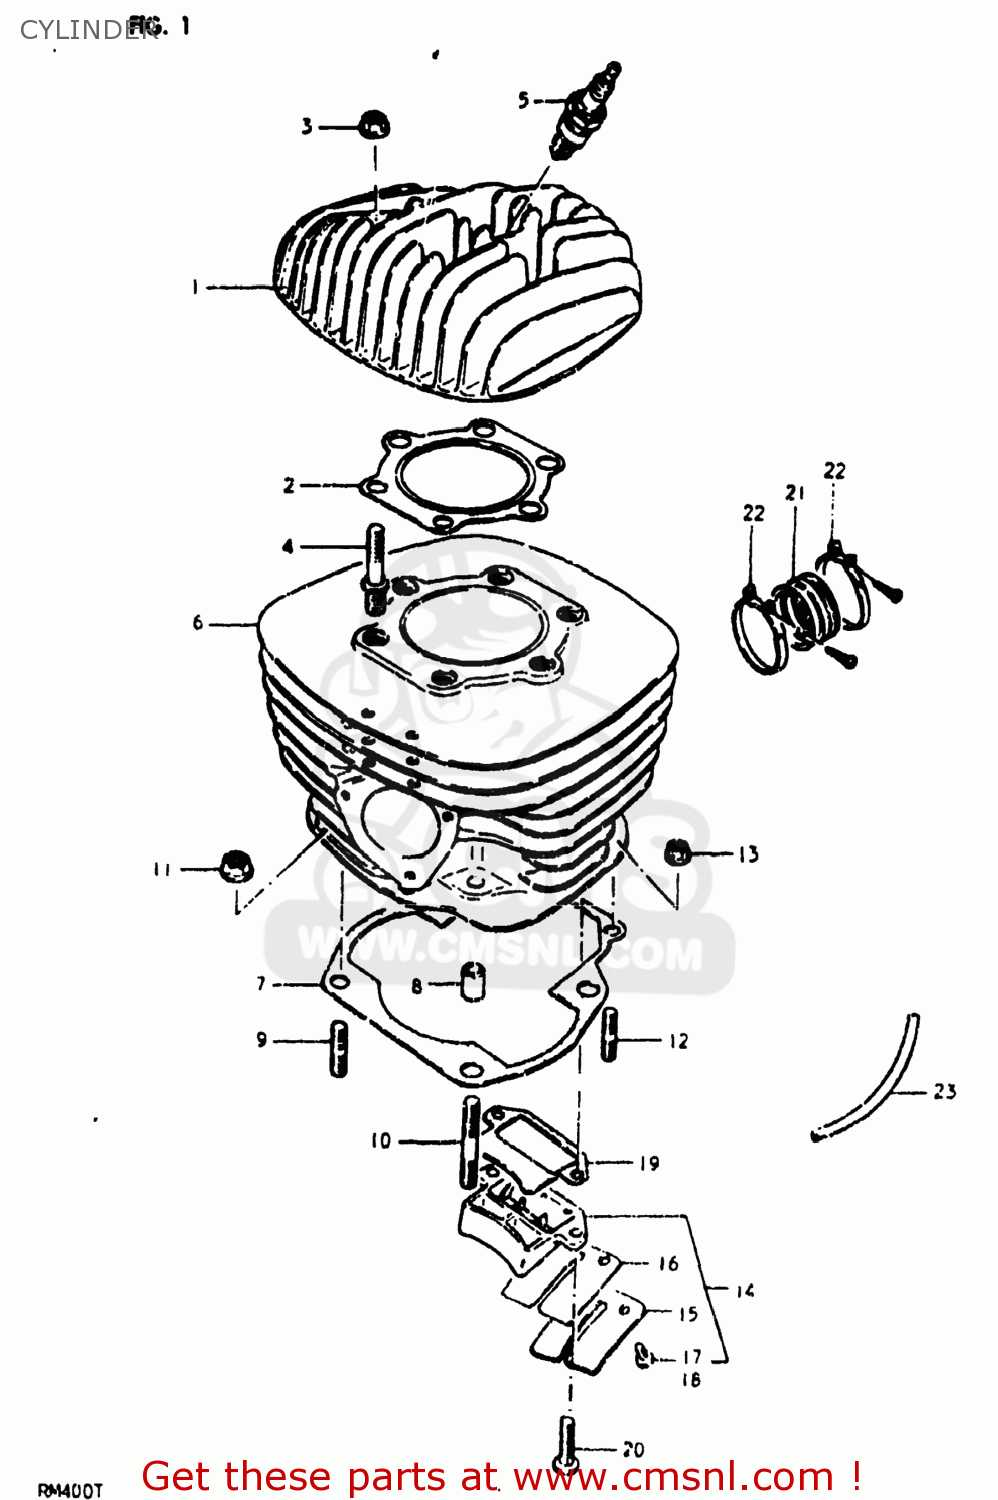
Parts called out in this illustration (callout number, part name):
1	HEAD,CYLINDER
2	GASKET,CYLINDER HEAD
3	NUT
4	STUD
5	PLUG,SPARK(NGK B-8EN)
6	CYLINDER
7	GASKET,CYLINDER (MCA)
8	PIN
9	STUD 10X30
10	STUD BOLT (L:45)
11	NUT
12	STUD 6X20
13	NUT
14	VALVE ASSEMBLY,REED
15	STOPPER,REED VALVE
16	VALVE,REED
17	SCREW
18	LOCK WASHER
19	GASKET,REED VALVE (MCA)
20	SCREW
21	PIPE,INTAKE
22	CLAMP
23	HOSE
